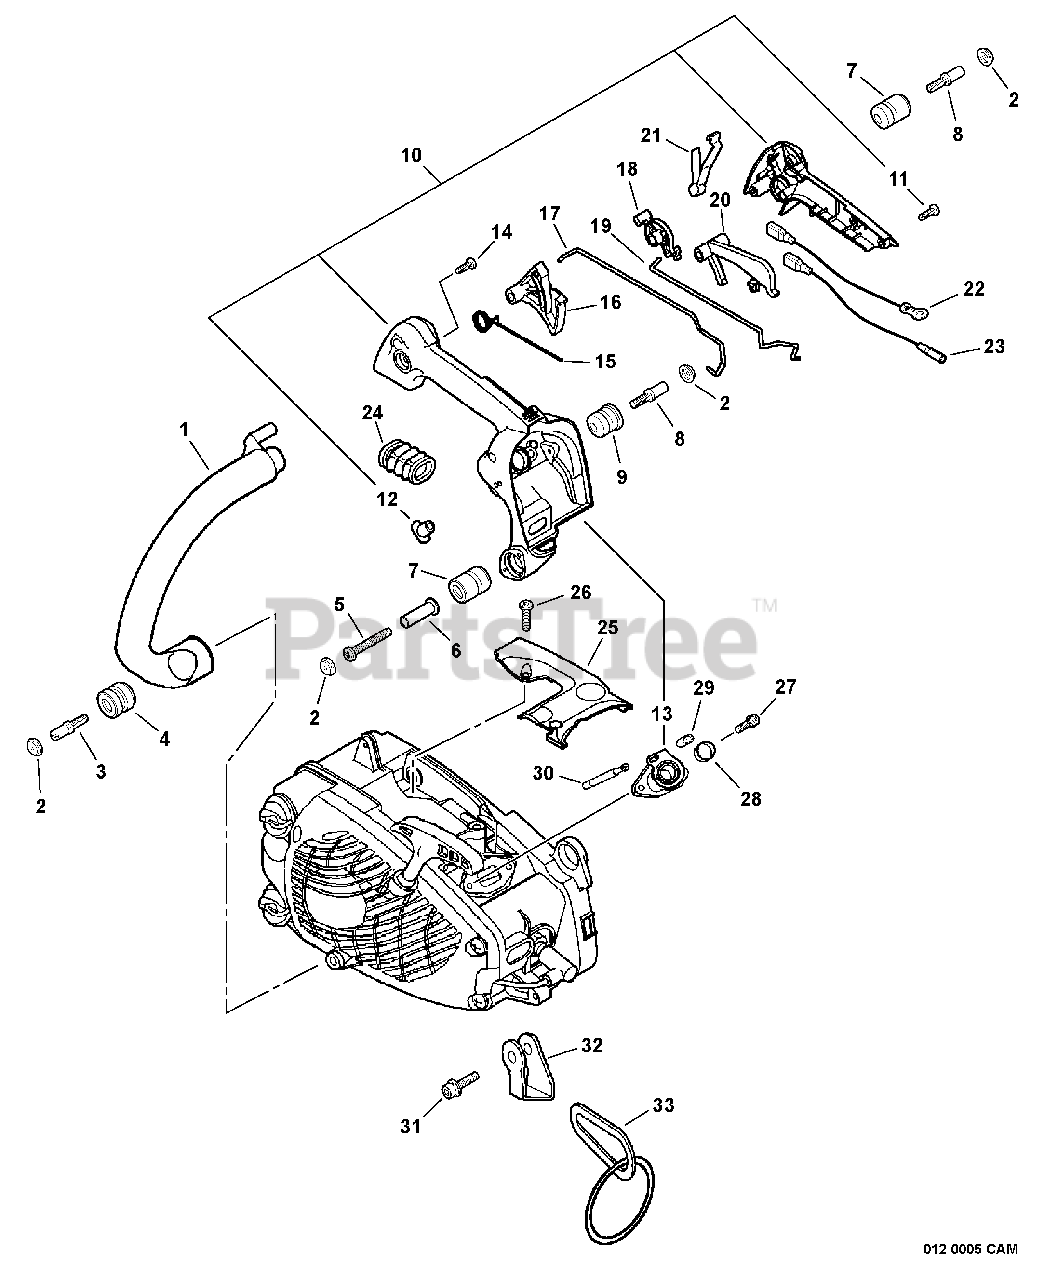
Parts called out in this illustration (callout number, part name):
1	HANDLE - FRONT
2	CAP, CUSHION
5	SCREW - 4X35 -- TAPPING
7	CUSHION
8	STUD, THREADED
9	CUSHION
10	HANDLE SET - REAR
11	SCREW - 4X16
13	BELLOWS, INTAKE
14	SCREW - 5X20 -- TAPPING
15	SPRING, TRIGGER
16	TRIGGER, THROTTLE
17	ROD, THROTTLE
18	LEVER, CHOKE
19	ROD, CHOKE
20	LEVER, TRIGGER LOCKOUT
21	TERMINAL - GROUND
22	LEAD - GROUND
23	LEAD - IGNITION
24	BELLOWS, INTAKE
25	COVER, DUST
26	SCREW - 4X12 -- TAPPING
27	SCREW - 5X12
28	COLLAR - 16
29	ADAPTOR
30	PIPE
31	SCREW - 4X25
32	BRACKET, STRAP
33	HANGER KIT
